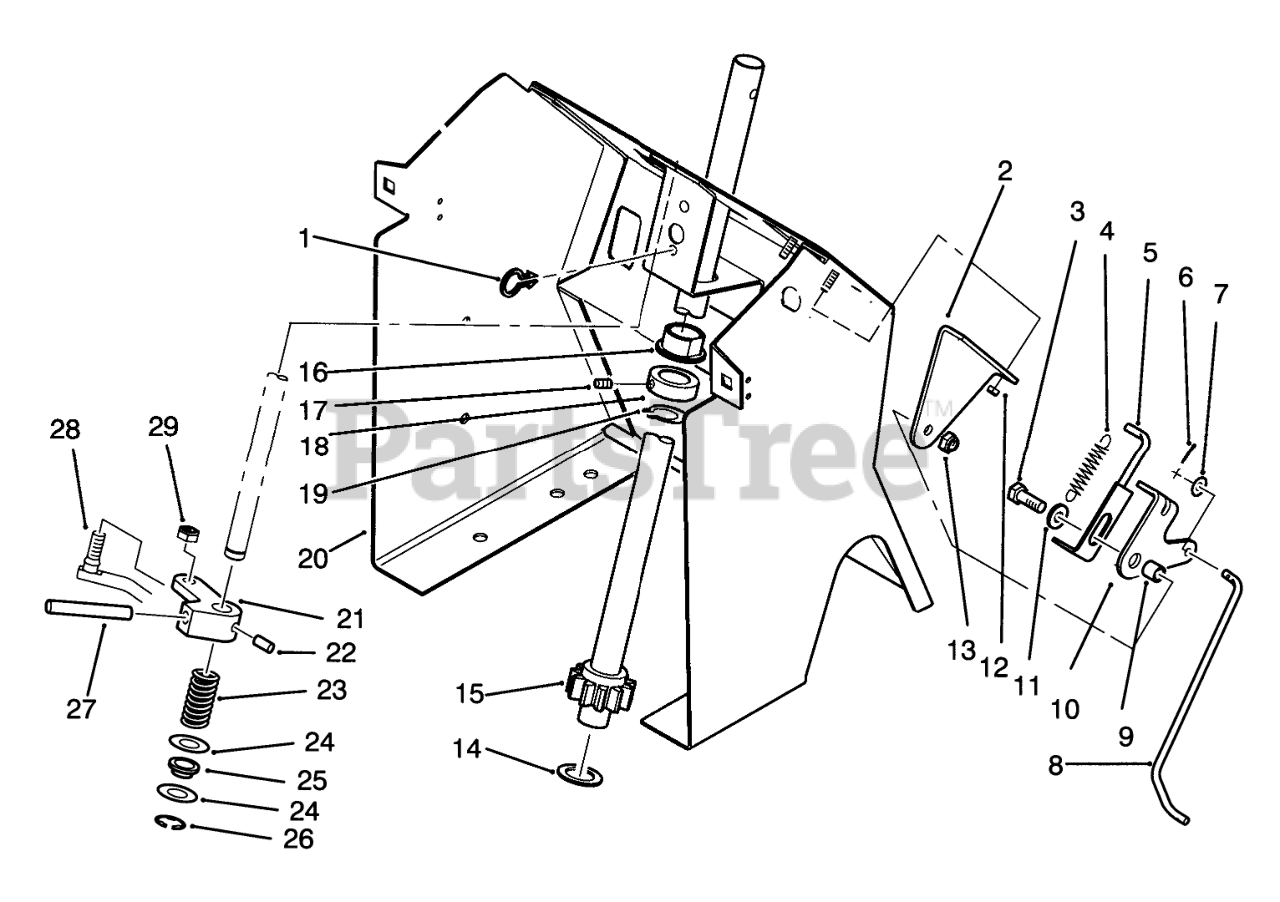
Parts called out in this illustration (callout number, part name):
1	CLIP-SNAP IN
2	SUPPORT-INDICATOR B
3	SCREW-HH
4	SPRING-EXTENSION
5	WLDMT-INDICATOR R
6	Cotter Pin
7	WASHER-FLAT
8	ROD-INDICATOR
9	SPACER
10	RETAINER-INDICATO B
11	WASHER-FLAT
12	Nut
13	NUT-LOCK, NI
14	WASHER
15	WLDMT-STRG SHAFT
16	COLLAR
17	SCREW-HSH
18	BEARING-FLANGED
19	RING-RETAINING
20	HOOD STAND W/A B
21	ARM-SPEED CONTROL
22	Pin-Roll
23	SPRING-COMPRESSION
24	SHIM-WASHER
25	BUSHING-NYLINER
26	RING-SHAFT, EXT
27	PIN-SPIROL 5/16X2.25
28	ROD-SHIFT R
29	NUT-LOCK, NI
